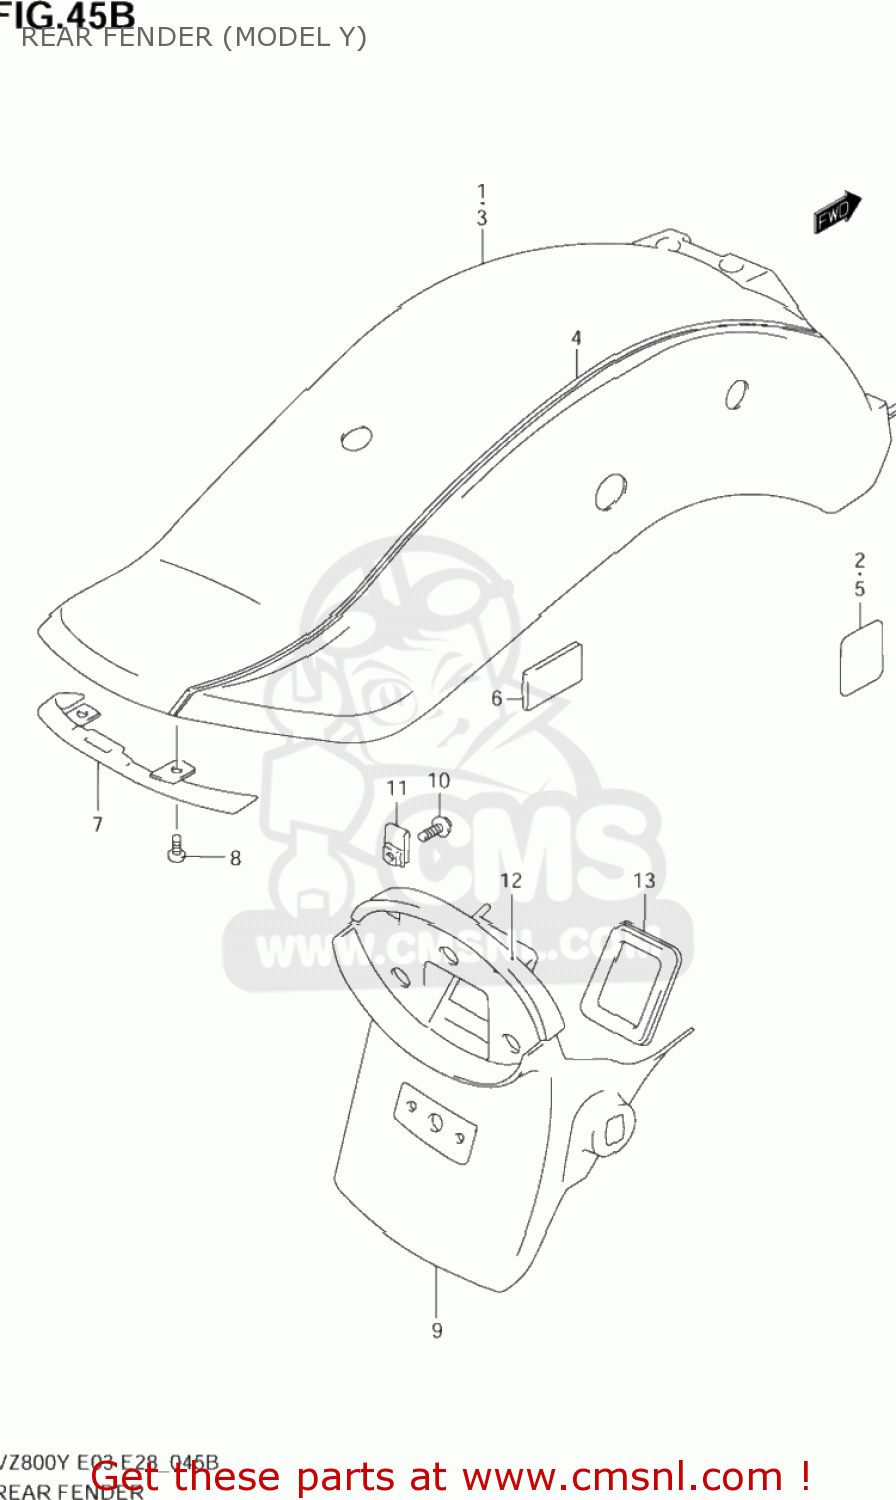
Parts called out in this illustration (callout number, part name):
1	FENDER,RR
2	PAD
3	FENDER,RR
4	TAPE SET
5	PAD
6	CUSHION
7	COVER,RR FENDER RR
8	SCREW
9	EXTENSION,RR FENDER
10	SCREW
11	PLATE,FRAME COVER
12	CUSHION,RR FENDER EXTENSION
13	CAP,RR FENDER EXTENSION
